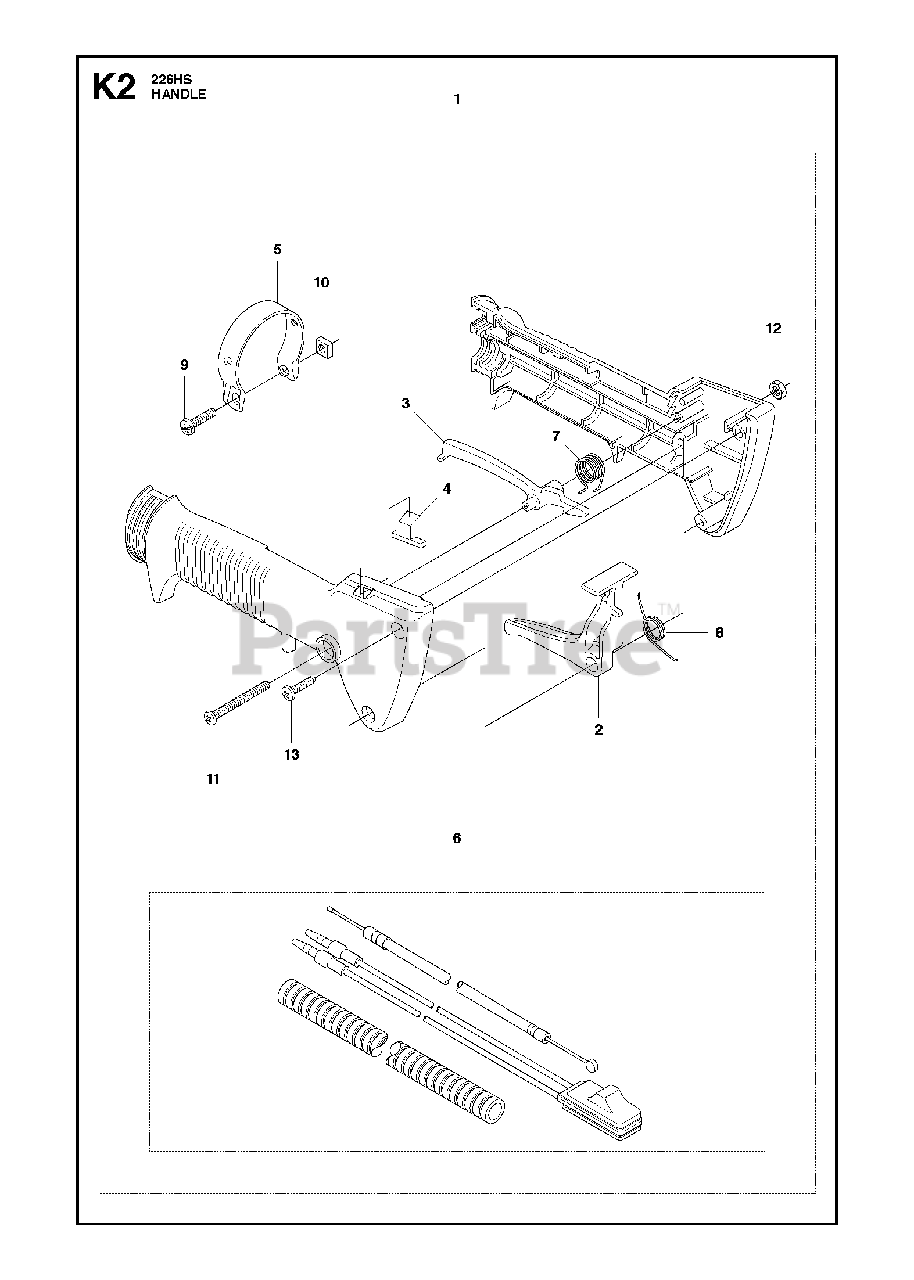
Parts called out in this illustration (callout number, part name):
1	LEVER ASSY
2	LEVER
3	LEVER
4	TOP
5	CLAMP
6	CABLE COMP
7	SPRING
8	SPRING
9	SCREW
10	NUT
11	SCREW
12	NUT
13	SCREW
